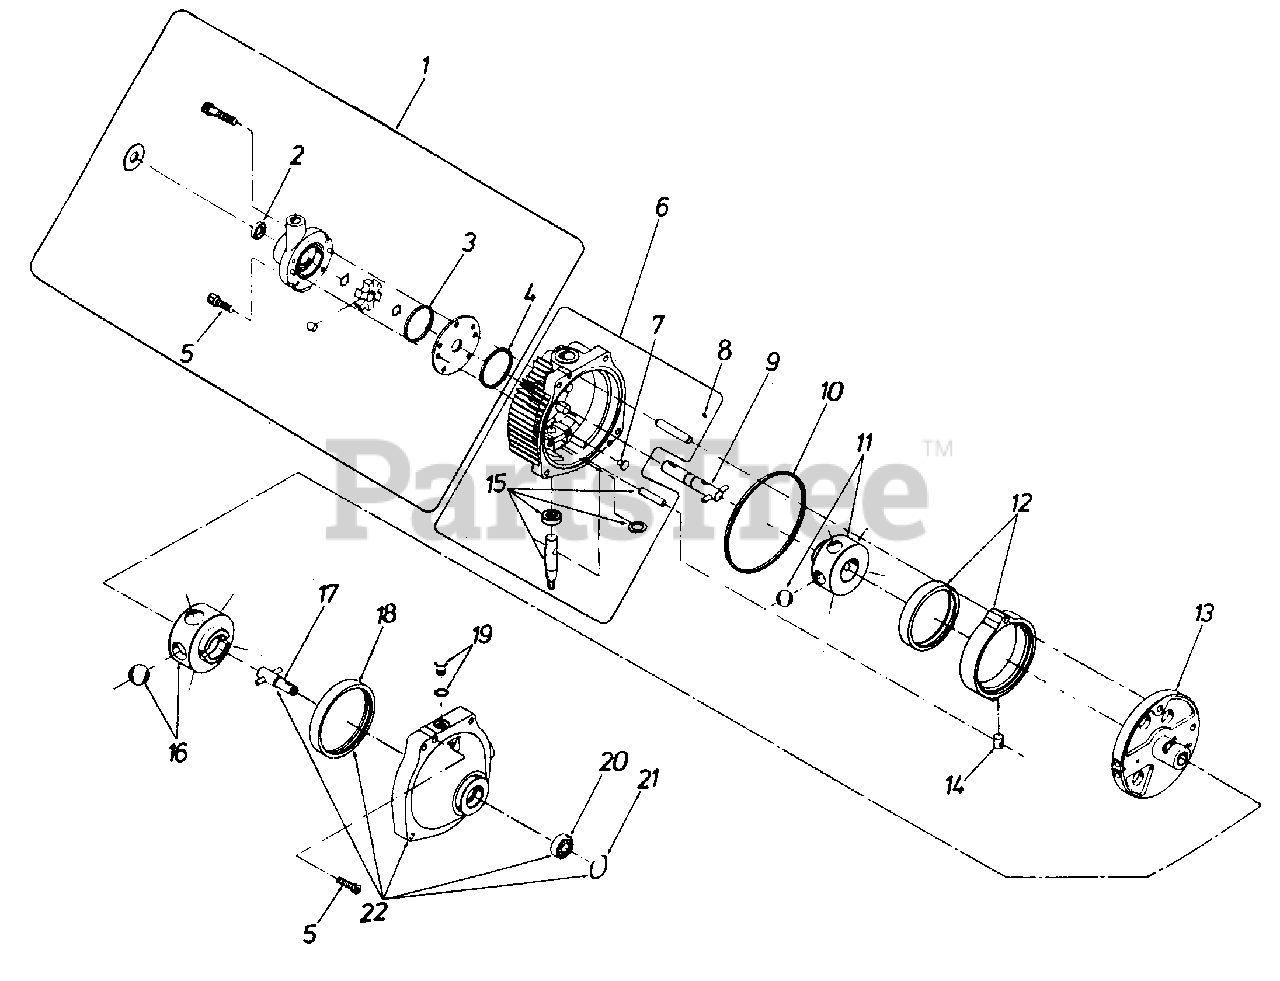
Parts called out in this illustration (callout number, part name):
1	Charge Pump Kit
3	Square Cut Seal Ring .036
4	Square Cut Seal Ring .038
5	Socket Head Cap Screw 5/16-18 x 1.25" Long
6	Cover Subassembly
7	Button
8	Drive Pin
9	Input Shaft Subassembly
10	Square Cut Seal Ring .166
11	Pump Rotor Ball Subassembly
12	Cam Ring Subassembly
13	Pintle Subassembly
14	Cam Ring Insert
15	Control Shaft Kit
16	Motor Rotor Ball Sub-assembly
17	Output Shaft Subassembly
18	Motor Race
19	O-Ring Plug Subassembly
20	Ball Bearing (Output)
21	Retaining Ring
22	Body Subassembly
